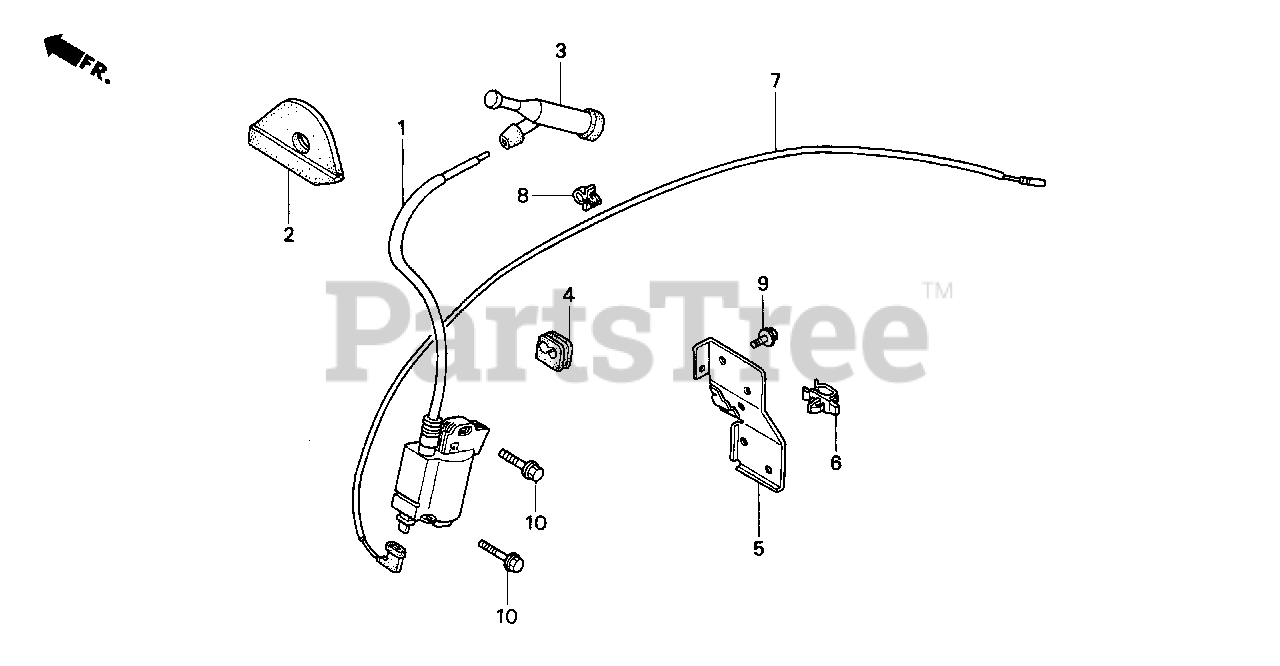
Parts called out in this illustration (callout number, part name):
1	COIL ASSY., IGNITION
2	SEAL, IGNITION
3	CAP ASSY., NOISE SUPPRESSOR (NICHIWA Y-EZA)
4	GROMMET, WIRE
5	BASE, HARNESS CLIP
6	CLIP B, HARNESS
7	WIRE, STOP SWITCH (430MM)
8	HOLDER, STOP SWITCH WIRE
9	BOLT, FLANGE (6X12) (CT200)
10	BOLT, FLANGE (6X28)
